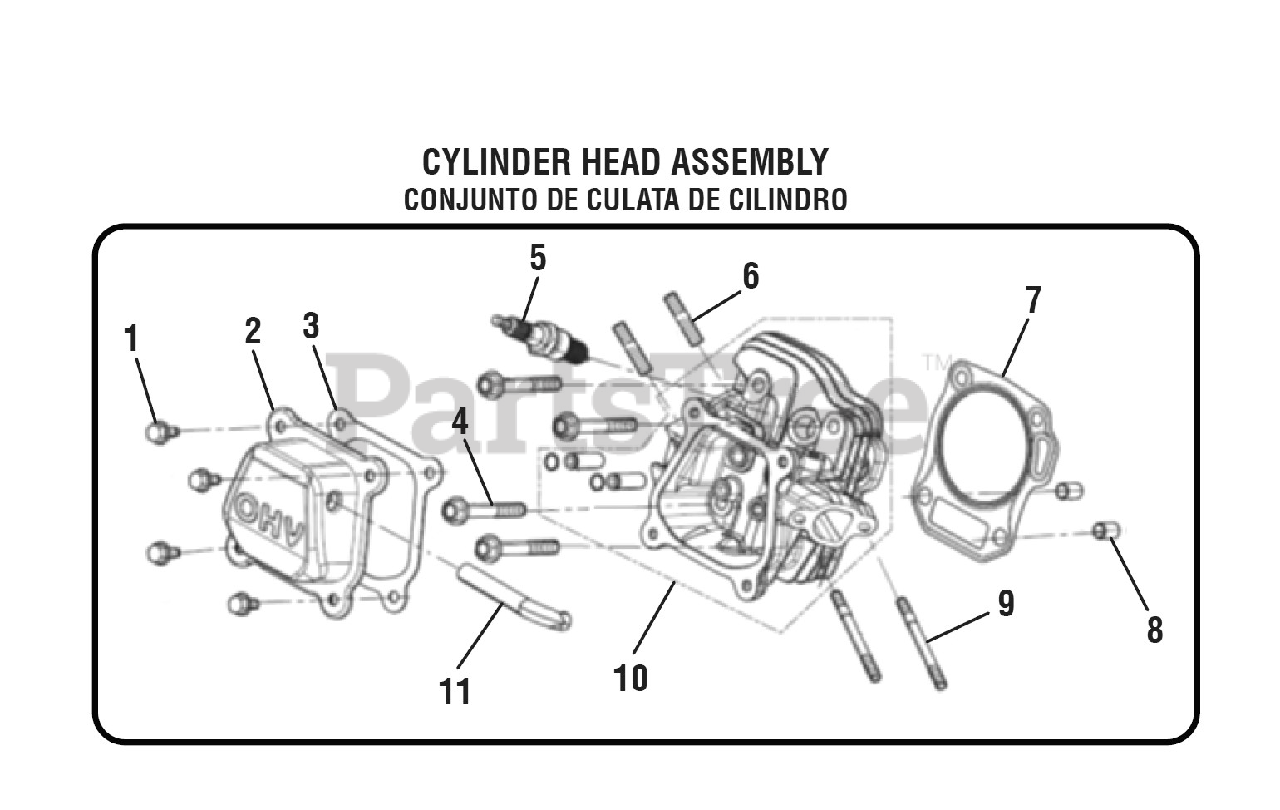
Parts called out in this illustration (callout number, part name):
2	Cylinder Head Cover Assembly
3	Cylinder Head Cover Gasket
4	Cylinder Head Bolt
5	Spark Plug
6	Stud
7	Cylinder Head Gasket
9	Stud
10	Cylinder Head Assembly
11	Breather Tube
